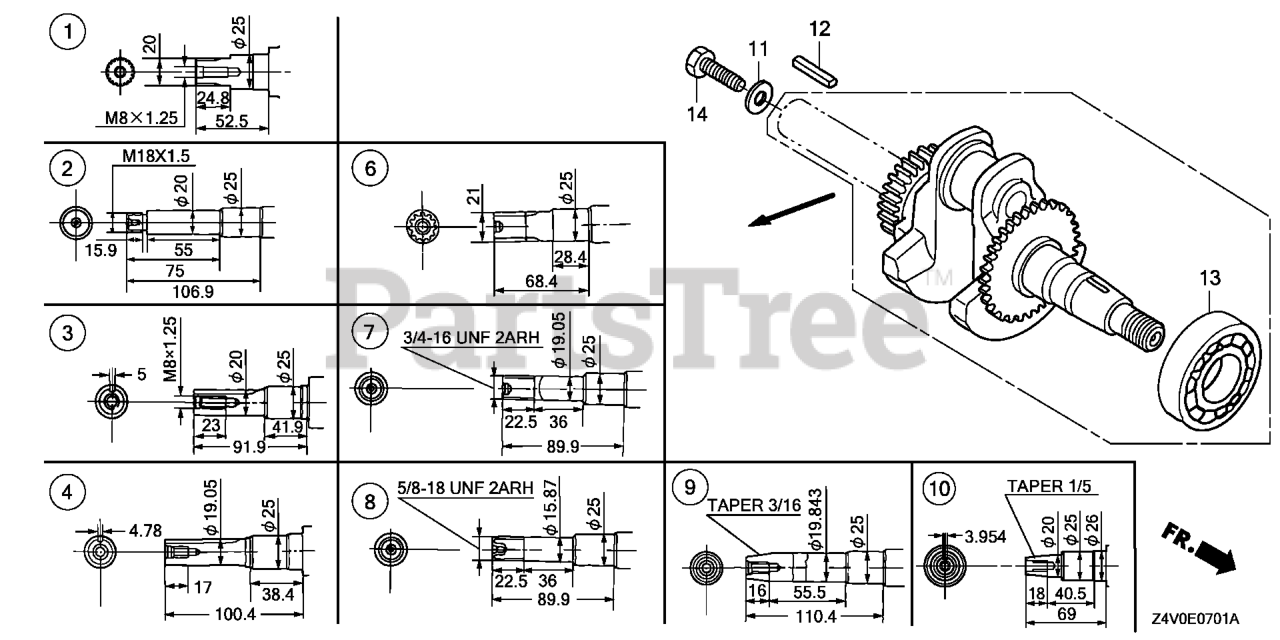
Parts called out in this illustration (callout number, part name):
2	CRANKSHAFT
13	BEARING, RADIAL BALL (6205)
13	BEARING, RADIAL BALL (6205) (NSK)
